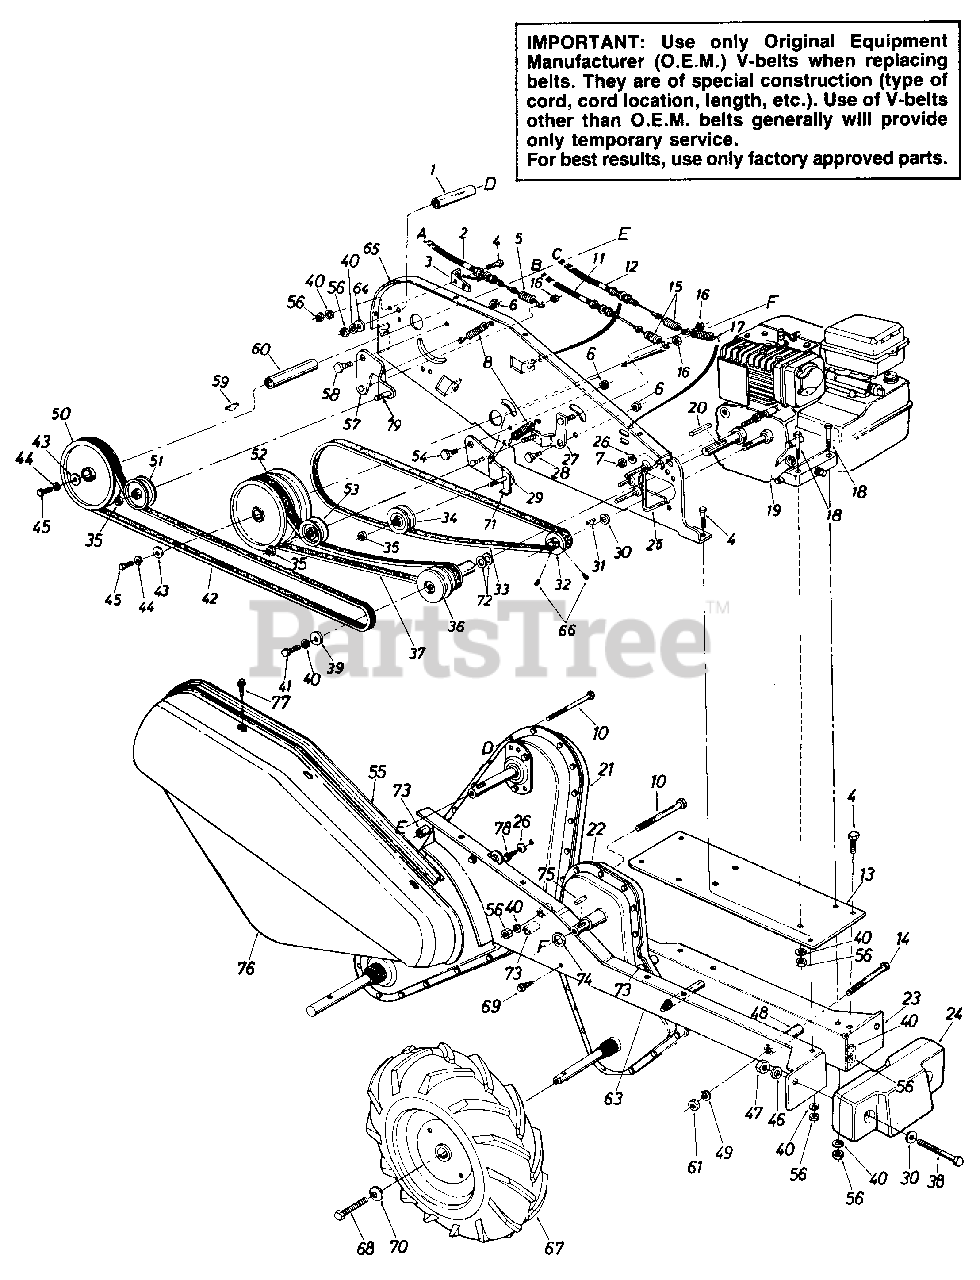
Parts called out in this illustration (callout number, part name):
1	Spacer.375" I.D. x .5" O.D. x 2" Lg.
2	Clutch Control Cable
3	Clutch Cable Bracket
4	Hex Bolt 5/16-18 x .75" Lg.
5	Extension Spring .50" O.D. x 2.5" Lg.
6	Hex Cent. L-Nut 3/8-16 Thd.
7	Hex Nut 1/4-20 Thd.
8	Extension Spring .50" O.D. x 1.55" Lg.
10	Hex Bolt 5/16-18 x 3" Lg.
11	Clutch Control Cable 42" Lg.
12	Clutch Control Cable 42" Lg.
15	Springs
16	Hex Cent. L-Nut 1/4-20 Thd.
17	Extension Spring .41" O.D. x 2.05" Lg.
18	Hex Bolt 5/16-18 x 1.5" Lg.
19	Engine
20	Sq. Key 3/16 x 1.00" Lg.
21	Chain Case Comp. Tines
22	Chain Case Comp. Wheels
25	Belt Keeper
26	Bell-Wash. .265" I.D. x .75" O.D.
29	Idler Brkt. Ass'y.
30	Fl-Wash. .51" I.D. x 1.0"
31	#5 Hi-Pro-Key 1/8" x 5/8" Dia.
32	1/2" V-Pulley 2.25" O.D. x .503" I.D.
33	"V"-Belt
34	"V"-Belt Idler 2.62" O.D.
35	Hex Ins. L-Nut 3/8-24 Thd.
36	1/2" "V"-Pulley Ass'y.
37	"V"-Belt
38	Hex Bolt 1/2-13 x 4" Lg.*
39	Fl-Wash. .344" I.D. x 1.125"
40	L-Wash. 5/16" I.D.
41	Hex Bolt 5/16-24 x 1.00" Lg.
42	"V"-Belt
43	Fl-Wash. 1/4" I.D. x .93" O.D.
44	L-Wash. 1/4" I.D.
45	Hex Bolt 1/4-28 x .75" Lg.
46	L-Wash. 1/2" I.D.
47	Hex Nut 1/2-13 Thd.
48	Spacer .38" I.D. x .62" O.D. x 2.18" Lg.
49	L-Wash. 818" I.D.
50	Fl-Pulley w/Flanges 6" O.D.
51	Fl-ldler w/Flanges 3.75" O.D.
52	Double Fl-Pulley 5/8" I.D.
53	Fl-ldler w/Flanges 2.12" O.D.
54	Shld. Bolt .500" Dia. x .l70" Lg.
55	Flange Extension
56	Hex Nut 5/16-18 Thd.
59	#61 Hi-Pro-Key 3/16" x 5/8" Dia.
60	Spacer .647" I.D. x 2.75" Lg.
61	Hex Nut 3/8-24 Thd.
65	Side Plate Ass'y.
66	Set Scr. 1/4-28 x .25" Lg.
67	R.H. Wheel Ass'y. Comp. 13 x 5
68	Hex Bolt 5/16-24 x .62" Lg.
69	Hex Self-Tap Scr. 5/16-24 x 5" Lg
70	Bell-Wash. 5/16" I.D.
71	Belt Keeper Brkt.
72	Fl-Wash. .76" I.D. x 1.5"
73	Spacer .326" I.D. x.47" O.D. x 96" Lg
74	Fl-Wash. .635" I.D. x 1" O.D.
75	Sq. Key 3/16 x .75" Lg.
78	Hex Wash. S-Tap Scr. 1/4-20 x .38" Lg.
79	Hex Bolt 3/8-24 x 1.25" Lg.
